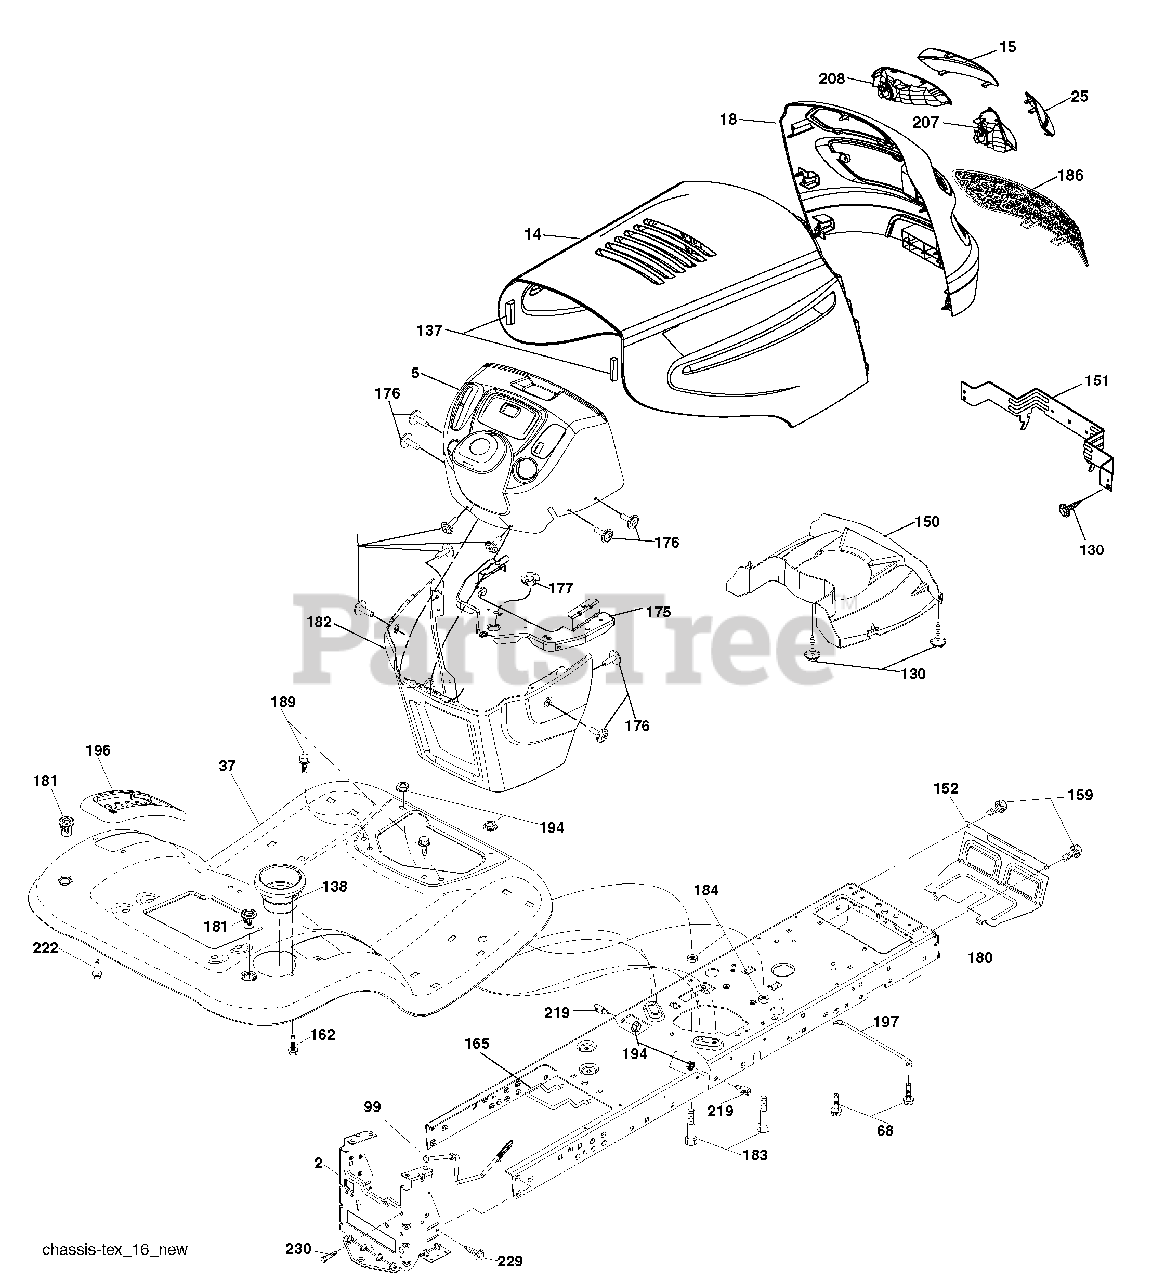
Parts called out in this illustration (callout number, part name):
2	Drawbar
5	Dash
14	Hood
15	Lens Grille LH
18	Grille
25	Lens Grille RH
68	Screw THDROL 5/16-18 x 1/2
99	Rod Bypass Asm
130	Screw 10 x 3/4 Single Lead-Hex
137	Bumper Hood
138	Cupholder
150	Duct Heat Hood
151	Bracket Pivot
152	Shield Browning/Debris
159	Screw Hexwsh Thdrol 3/8-16 x 3/4
162	Screw Hex Wsh Hi-Lo 1/4 x 1/2 unc
165	Bracket Support Tank
175	Crossmember
176	Screw 10-24 x 5/8 Wshd Qdrx
177	Bushing Steering
181	Bushing Mtg. Fender Crgo.
182	Dash Lower
183	Bolt Fin Hex 5/16-18 x 1-1/4
184	Spacer Fender
189	Screw 5/16-18 x 3/4
194	Nut Lock Hex Flange 5/16-18
196	Console Asm. Deck Lift
197	Rod Pivot Chassis
207	Bezel RH
208	Bezel LH
219	Stud Fastener
222	Screw thd Roll 1/4-20 x 5/8
229	Screw 3/8-16 x 1
230	Bolt Shoulder 5/16-18
230	Plug Cruise/Hook/Phone
